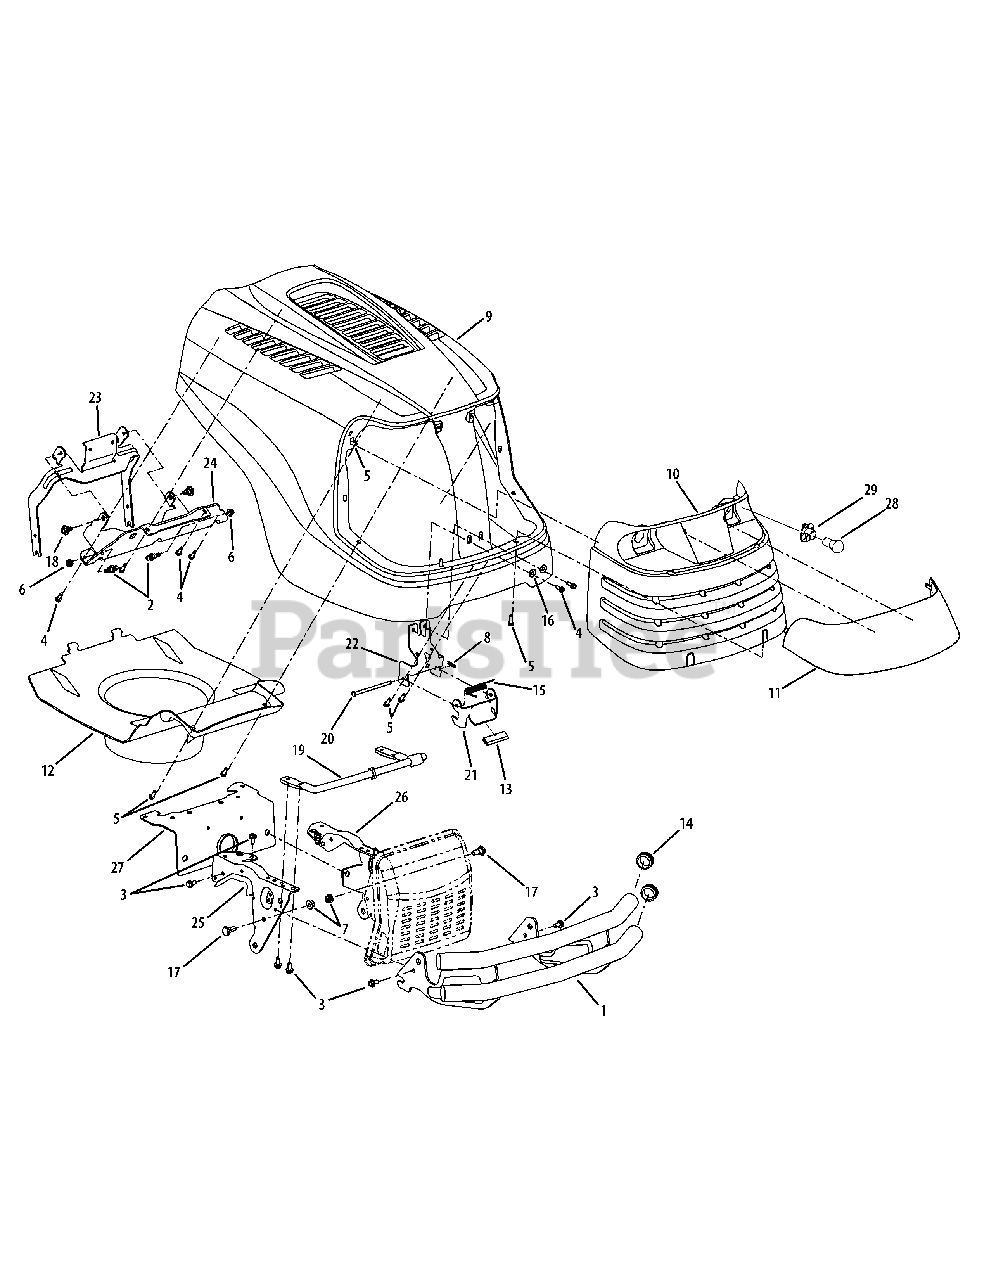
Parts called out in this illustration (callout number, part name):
2	Bolt, Ball Shoulder, 5/16-18 x .48
3	Screw, Hex, 5/16-18 x .750
4	Screw, Self Tapp, 1/4-20 x.750
5	Screw, 1/4-15 x.750
6	Nut, Flange Lock, 5/16-18
7	Nut, Nylon Lock, 3/8-16
8	Pin, Cotter,.072 Dia. x 1.13
9	Hood, Service Kit
9	Hood
10	Grill
11	Lens
12	Hood Plenum
13	Vinyl Strip, 2.5"
14	Cap, Bumper
15	Latch Spring
16	Washer, Flat, .28 x .74 x .063
17	Screw, Shoulder, 3/8-16
18	Screw, Shoulder, 5/16-18
19	Hood Latch Rod
20	Rod,.250 Dia. x 4.55
21	Latch Pivot Bracket
22	Latch Plate
28	Miniature Lamp, 12V
29	Lamp Socket
